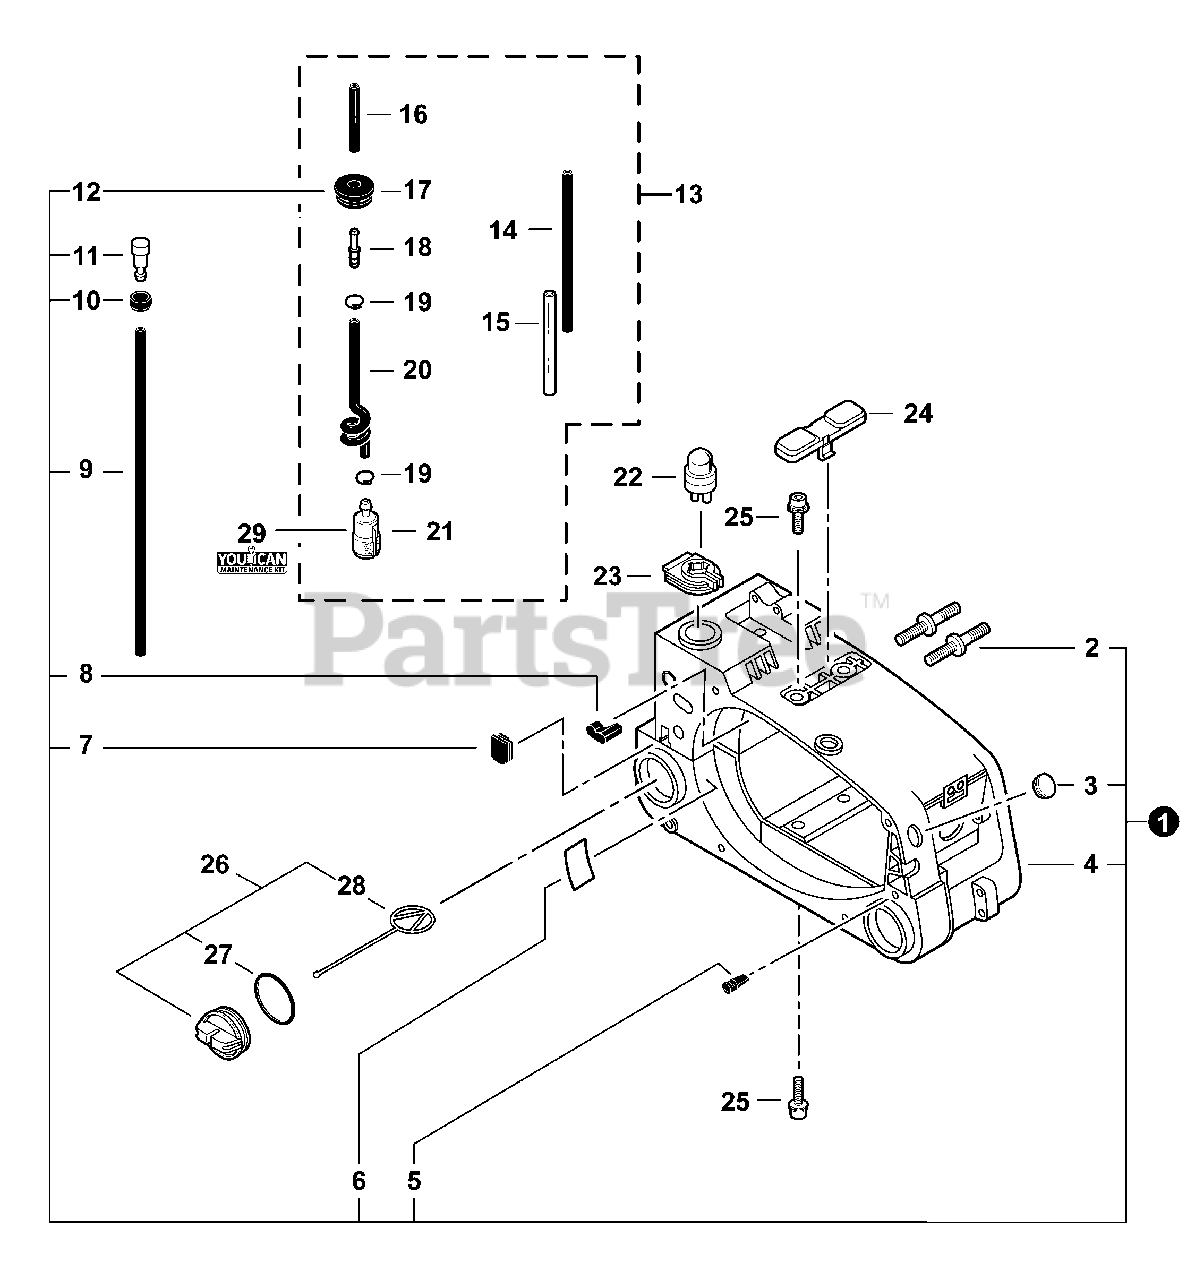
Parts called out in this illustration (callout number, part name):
1	COVER ASSY, ENGINE
2	BOLT, STUD 6
4	COVER, ENGINE
5	VENT ASSY
6	SHIELD, HEAT
9	PIPE, FUEL 3×5×150 BLACK
10	HOLDER, VENT
11	VENT ASSY
12	GROMMET, FUEL
13	FUEL SYSTEM KIT
14	PIPE, FUEL 3x-5x-70 BLACK
15	PIPE, FUEL 2×4×42 CLEAR
16	PIPE, FUEL 3×6×36 BLACK
17	GROMMET, FUEL
18	CONNECTOR, PIPE Ø5ר3.5
19	CLIP Ø6.5 MM
20	PIPE, FUEL 3×6×56 BLACK
21	FILTER, FUEL
22	BULB, PURGE
23	BRACKET, BULB
24	COVER, TOP
25	BOLT 5×16
26	CAP ASSY, FUEL - ORANGE
28	CONNECTOR, CAP L= 60 MM
29	TUNE-UP KIT - YOUCANT
